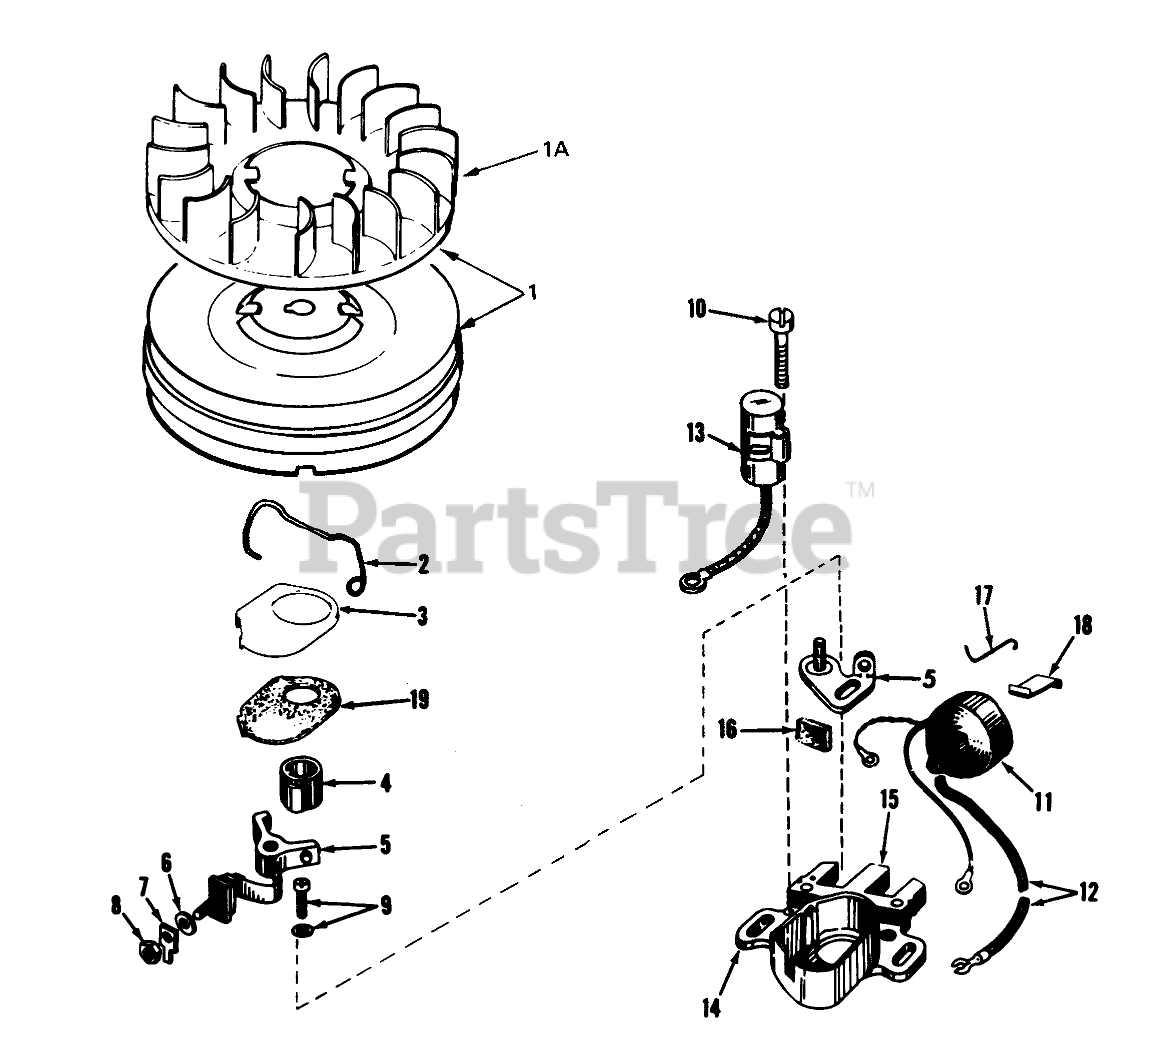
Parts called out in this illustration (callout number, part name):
1	Flywheel (Incl. No. 1A)
2	Spring Breaker Box
3	Cover-Dust
4	Cam-Breaker
5	Breaker Assy.
7	Terminal, Ground
9	Breaker Screw
10	Condenser Screw
11	Coil Assy. (Incl. No. 12)
12	Wire, Lead
13	Condenser
14	Core & Plate
15	Stator Assy. (Incl. Nos. 2, 3, 5 thru 14 & 16 thru 19)
16	Felt,Cam Wiper
17	Clip, Coil
18	Spring Coil Wedge
19	Gasket-Dust Cover
19	Gasket, Dust Cover
